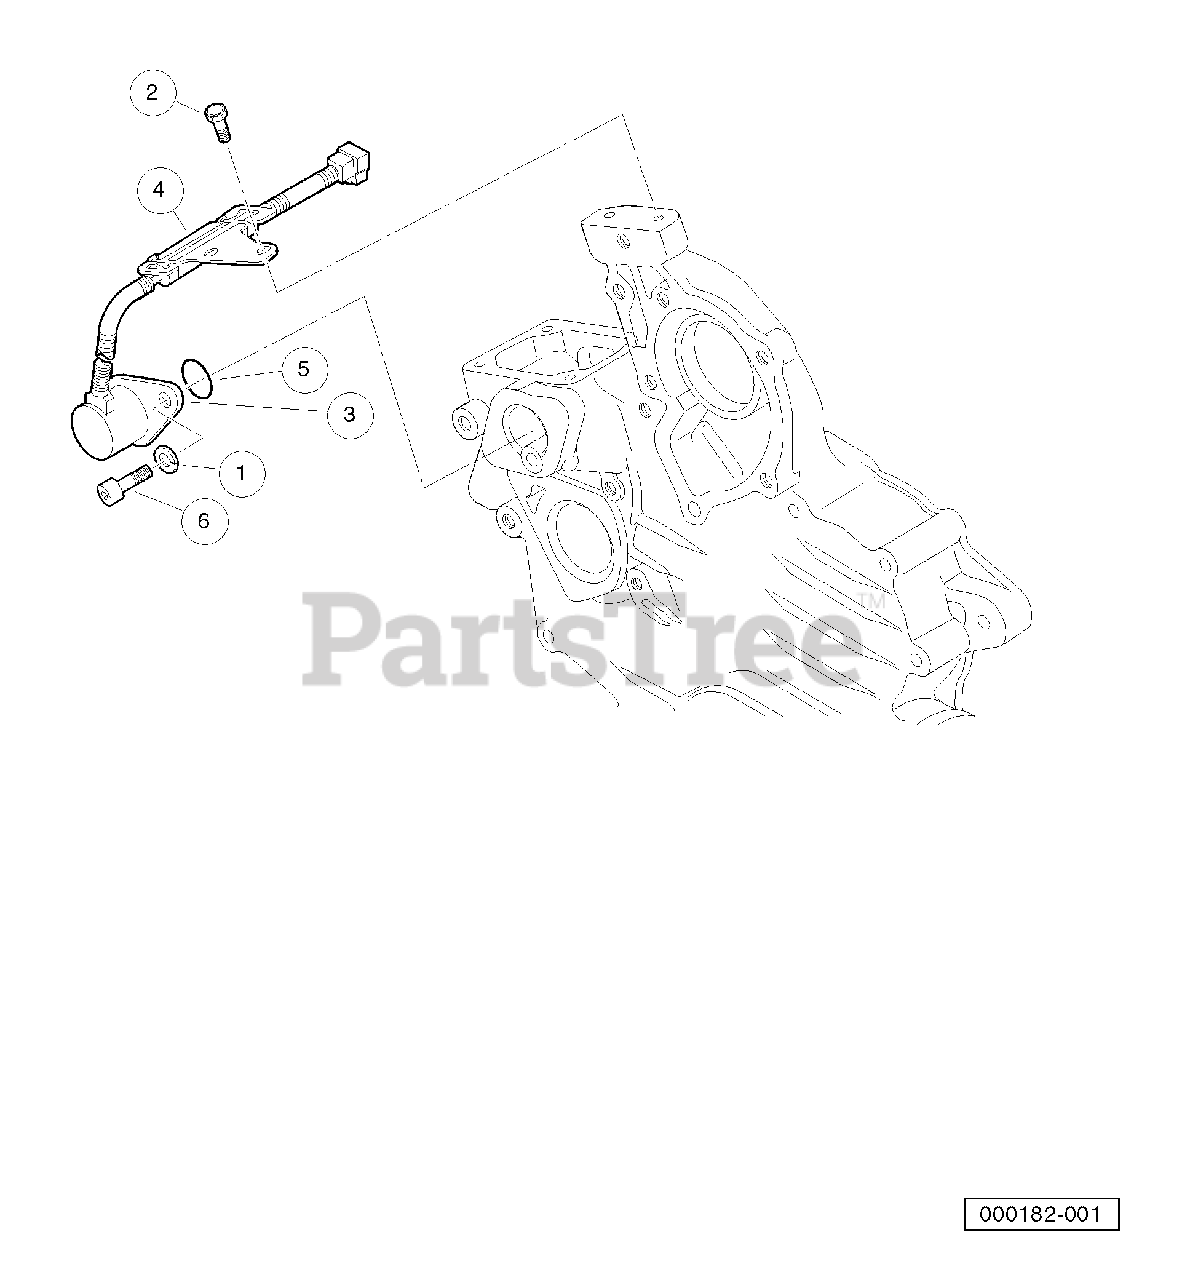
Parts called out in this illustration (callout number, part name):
1	Washer, Spring, M6, D722
2	Bolt, Solenoid, Stop, D722
3	Solenoid, Stop
4	Stay, Stop Solenoid
5	O-Ring, Stop Solenoid
6	Bolt, Stop Solenoid
